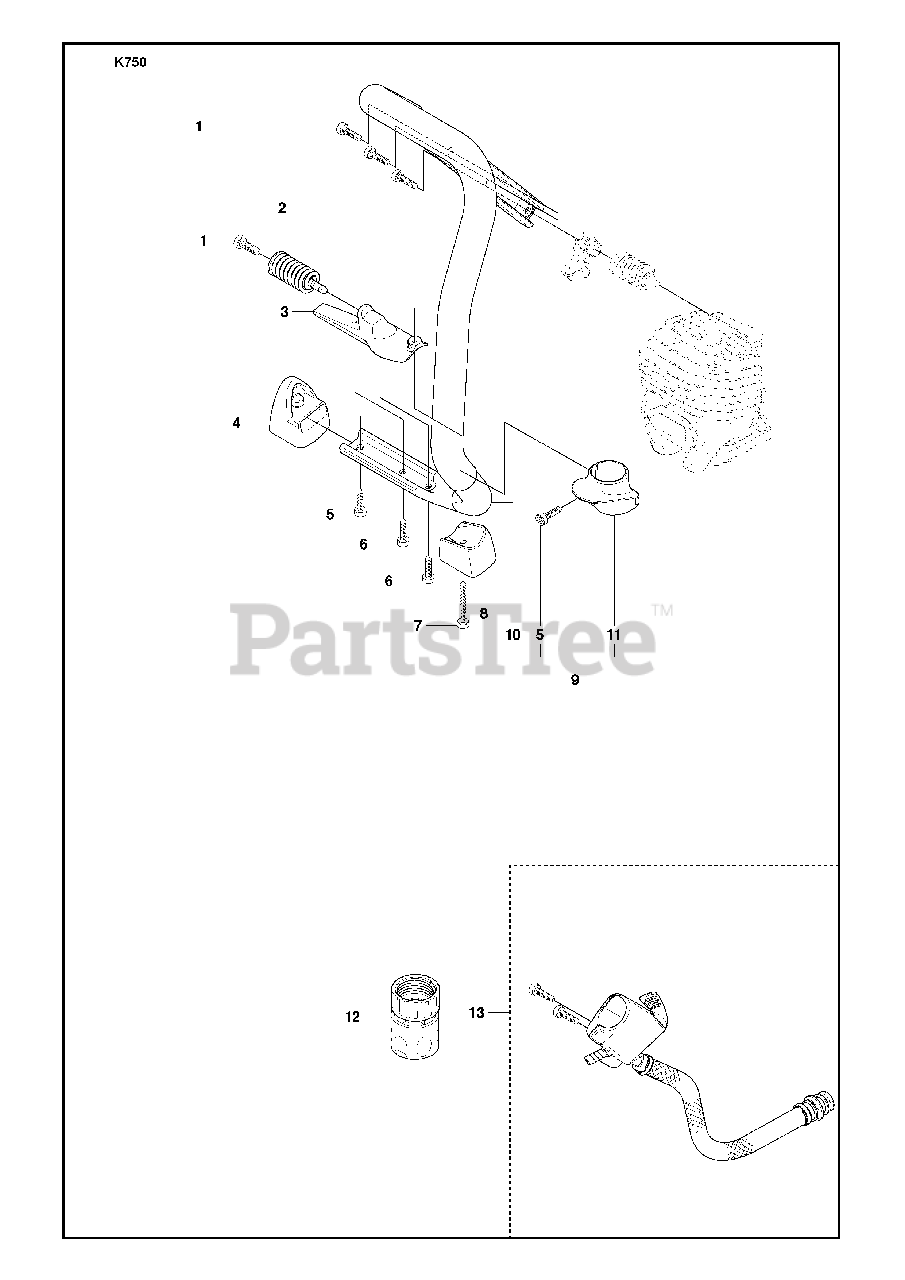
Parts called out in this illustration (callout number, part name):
2	Av-Element
3	Spring Retainer
4	Ground Support
8	Ground Support
9	Handle
10	Front Handle
12	Coupler
